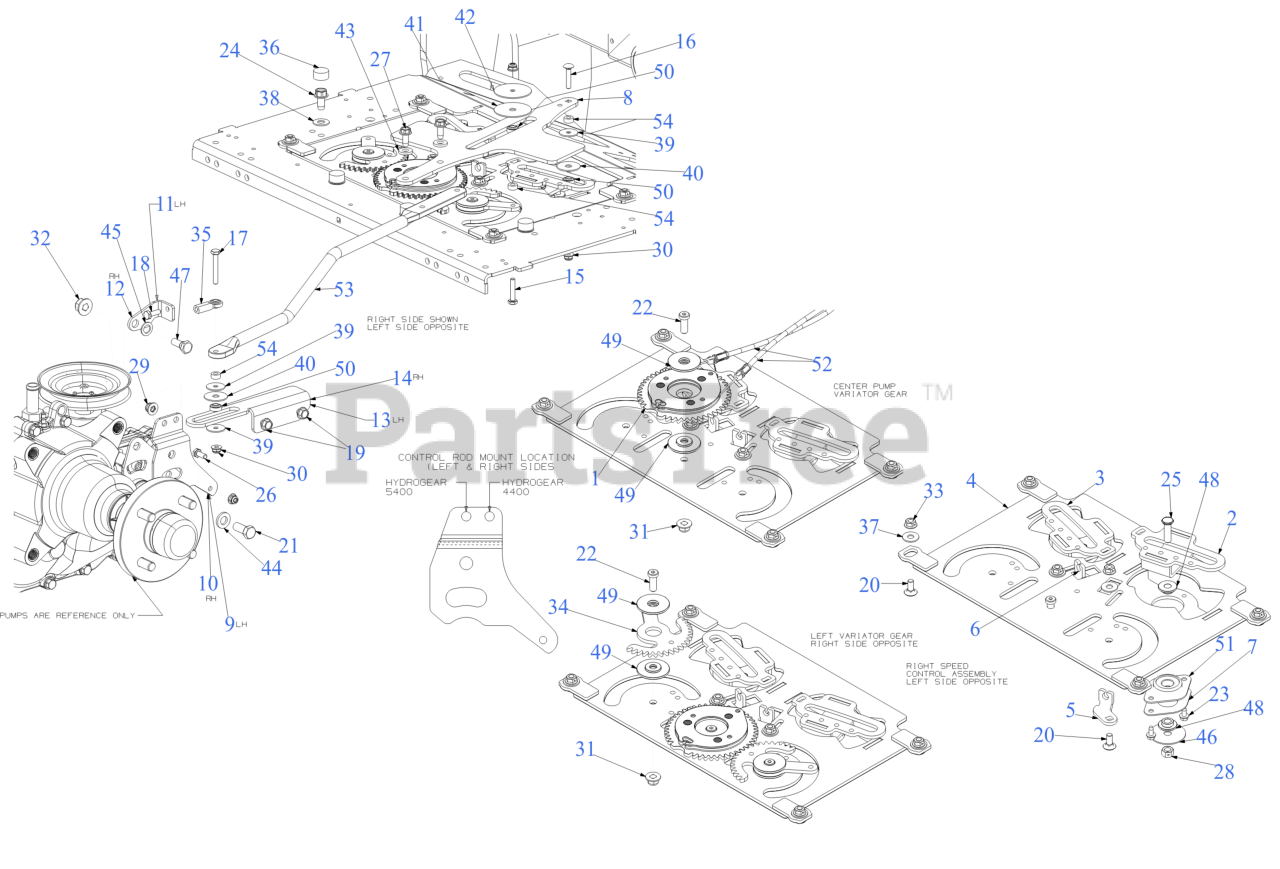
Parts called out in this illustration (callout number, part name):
2	PUMP CONTROL CAM ASSEMBLY (RH)
3	PUMP CONTROL CAM ASSEMBLY (LH)
4	PUMP CONTROL MOUNTING BRACKET
5	STEERING CABLE BRACKET
6	STEERING CABLE BRACKET
7	RETAINING PLATE
8	STEERING PUMP ACTUATOR ARM
9	NEUTRAL MOUNT BRACKET (LH)
10	NEUTRAL MOUNT BRACKET (RH)
11	CONTROL PUMP BRACKET (LH)
12	CONTROL PUMP BRACKET (RH)
13	GUIDE ARM BRACKET (LH)
14	GUIDE ARM BRACKET (RH)
15	HEX SCREW 1/4-20 x 1.25
16	CARRIAGE BOLT 1/4-20 x 1.25 Gr5
17	HEX SCREW 1/4-20 x 1.75
18	HEX SCREW 1/4-28 x .75
19	SCREW 5/16-18 x .750
20	CARRIAGE BOLT 5/16-18 x .75
21	SCREW 7/16-14 x 1.00 GR5
22	SCREW 3/8-16 x 1
23	SCREW 1/4-20 X.500
24	SCREW 3/8-16 x 3/4
25	SCREW 3/8-16 x 1.25 GR5
26	SCREW 1/4-20 x .620 GR5
27	SCREW 5/16-18 x .750
29	FLANGE LOCK NUT 5/16-18
30	FLANGE LOCK NUT
32	HEX FLANGE LOCK NUT 7/16-14
33	HEX FLANGE NUT
34	STEERING GEAR YOKE
35	END ROD (RH)
36	SLIDE CAP
37	FLAT WASHER
38	FLAT WASHER
39	FLAT WASHER
40	WASHER .355X1.25X.06THK
41	FLAT WASHER
42	FLAT WASHER
43	FLAT WASHER.344X.75X.1
44	FLAT WASHER
45	FLAT WASHER .469X.750X.054
46	HUB CAP WASHER .406 x 1.92 x .060
47	SHOULDER SCREW .437
48	SHOULDER SPACER
49	SHOULDER SPACER
50	BALL BEARING .25 x .625 SPCL
51	BALL BEARING
52	TRANSMISSION CONTROL LINK CABLE
53	PUMP CONTROL ROD
